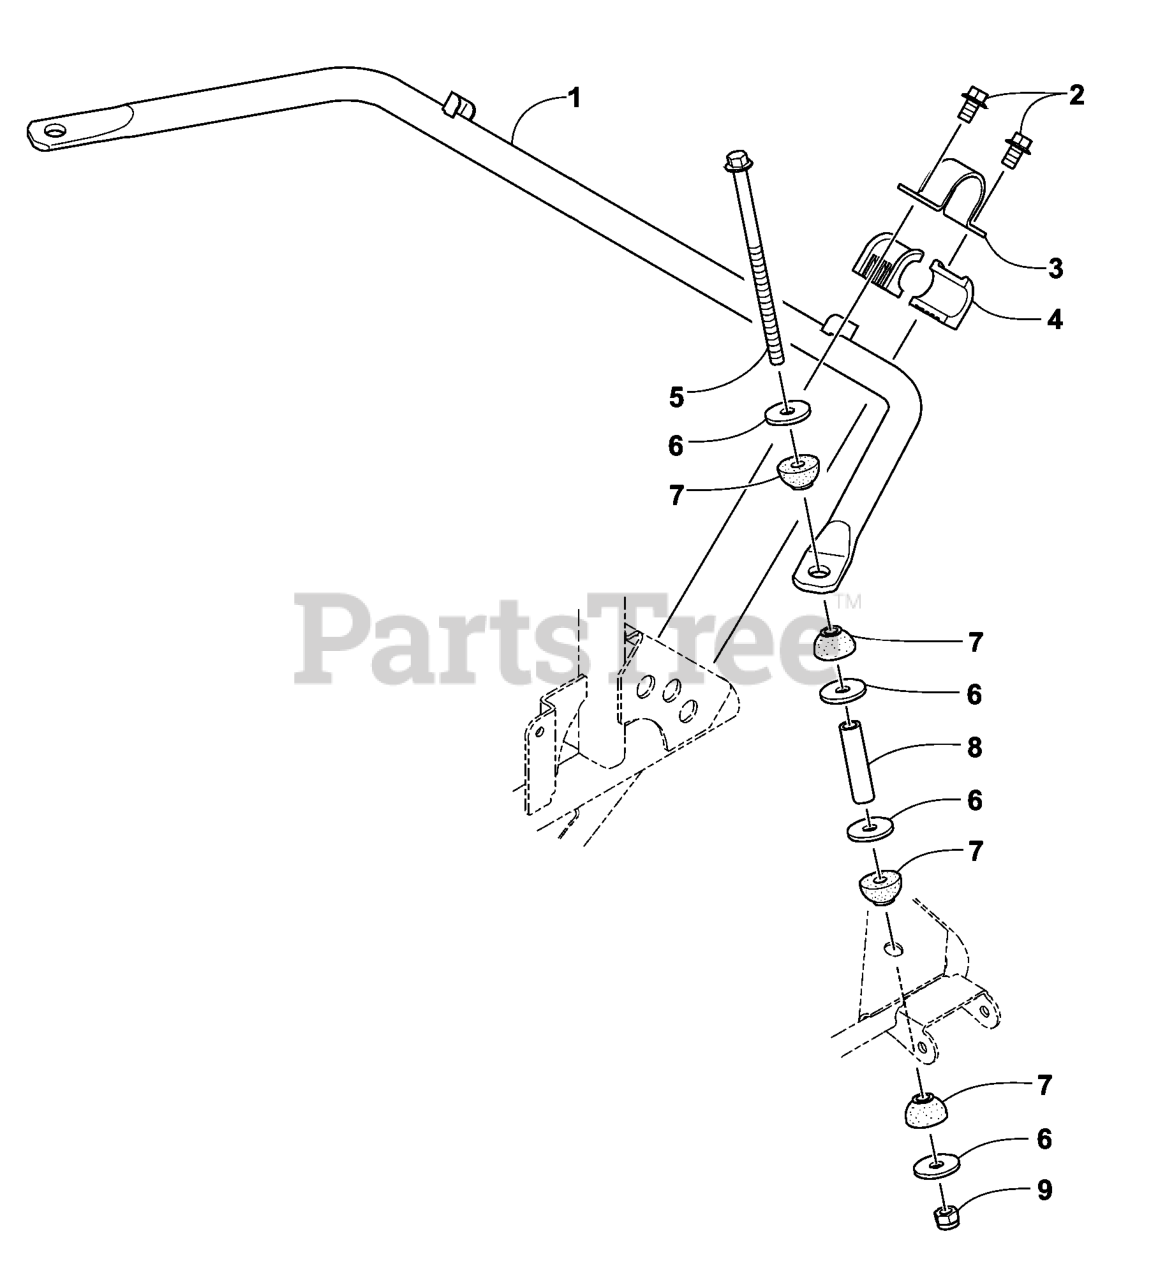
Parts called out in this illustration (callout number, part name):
1	SWAYBAR-REAR
2	SCREW-HFH
4	BUSHING-HALF, SWAYBAR
5	SCREW-HFH
6	WASHER-FLAT
7	BUSHING-SWAYBAR LINK
8	SPACER-SWAYBAR
